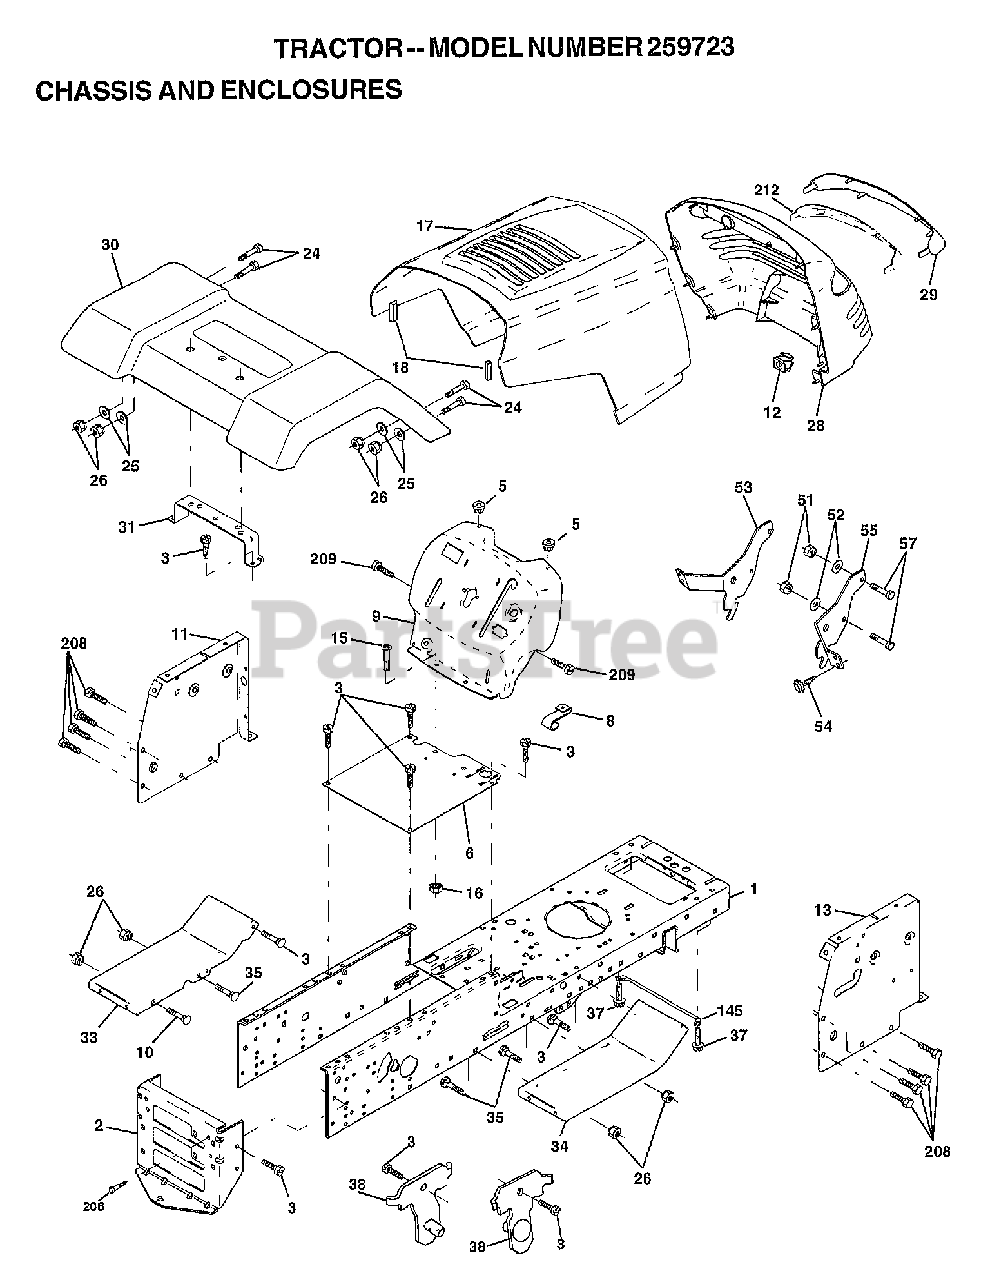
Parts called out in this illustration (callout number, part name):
2	DRAWBAR
3	SCREW
5	BUMPER-HOOD/DASH
6	SADDLE
8	CLIP.RETAINER
9	DASH
11	"PANEL-DASH,LH"
12	CLIP.TINNERMAN
15	SCREW
17	HOOD.STEEL.ASSY
24	BOLT
25	WASHER
26	NUT
28	GRILLE-MS428
29	LENS.GRILLE.PRIVATE LABEL
30	FENDER
31	BRKT FENDER
35	BOLT
37	SCREW LT
38	BRKT ASM PIVOT MOWER REAR
51	NUT
52	WASHER
53	BRACKET.GRILLE.LH
54	SCREW.HEX.WS.HD
55	BRACKET.GRILLE.RH
145	"ROD POVOT,CHASSIS"
206	BOLT SHOULDER
208	SCREW
209	SCREW
